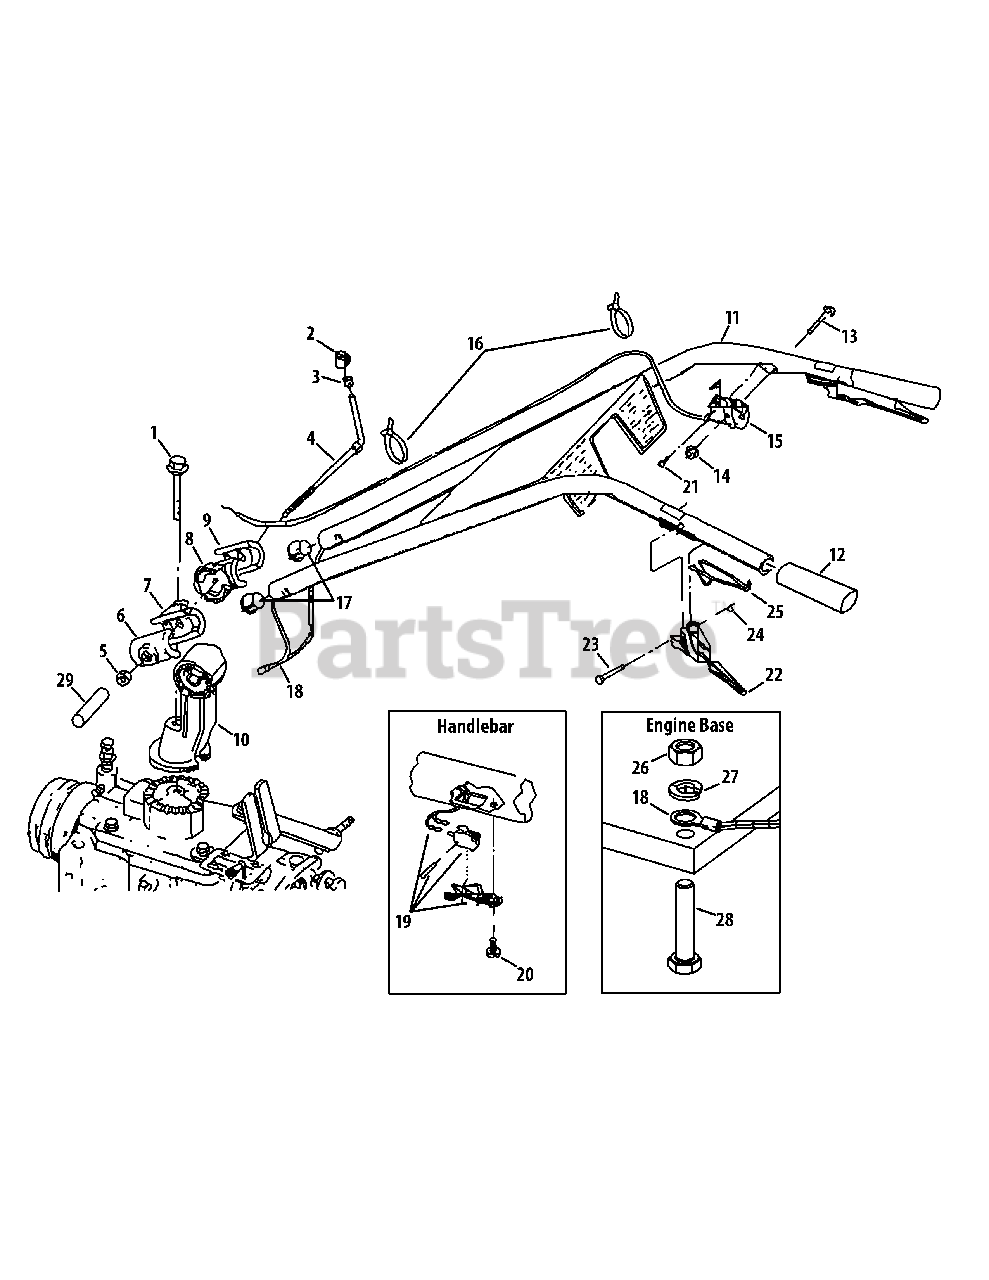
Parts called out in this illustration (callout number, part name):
1	Hex Bolt, 1/2-13 x 3-1/2
2	Handlebar Height Adjustment Knob
3	Retaining Ring
4	Handlebar Height Adjustment Stud
5	Hex Nut, 1/2-13
6	Handlebar Hgt, Adj. Clamp (LT)
7	Handlebar Hgt. Adj. Ratchet (LT)
8	Handlebar Hgt. Adj. Ratchet (RT)
9	Handlebar Hgt. Adj. Clamp (RT)
10	Handlebar Mounting Base
12	Handlebars Grip
13	Curved Head Bolt, 1/4-20 x 2"
14	Hex Nut, 1/4-20
15	Throttle Control & Cable, 66"
16	Plastic Tie
17	Wire Harness Retainer Plug
18	Handlebar Wire Harness Assembly
19	Switch Assembly
20	Pan Head Screw, #10-16 x 1/2
21	Phillips Head Screw, 10-32 x 1/2
22	Operator Presence Control Lever
23	Pivot Pin
24	Retaining Ring
25	Return Spring
26	Hex Nut, 5/16-18
27	Washer, 5/16
28	Hex Head Screw, 5/16-18 x 1.5
